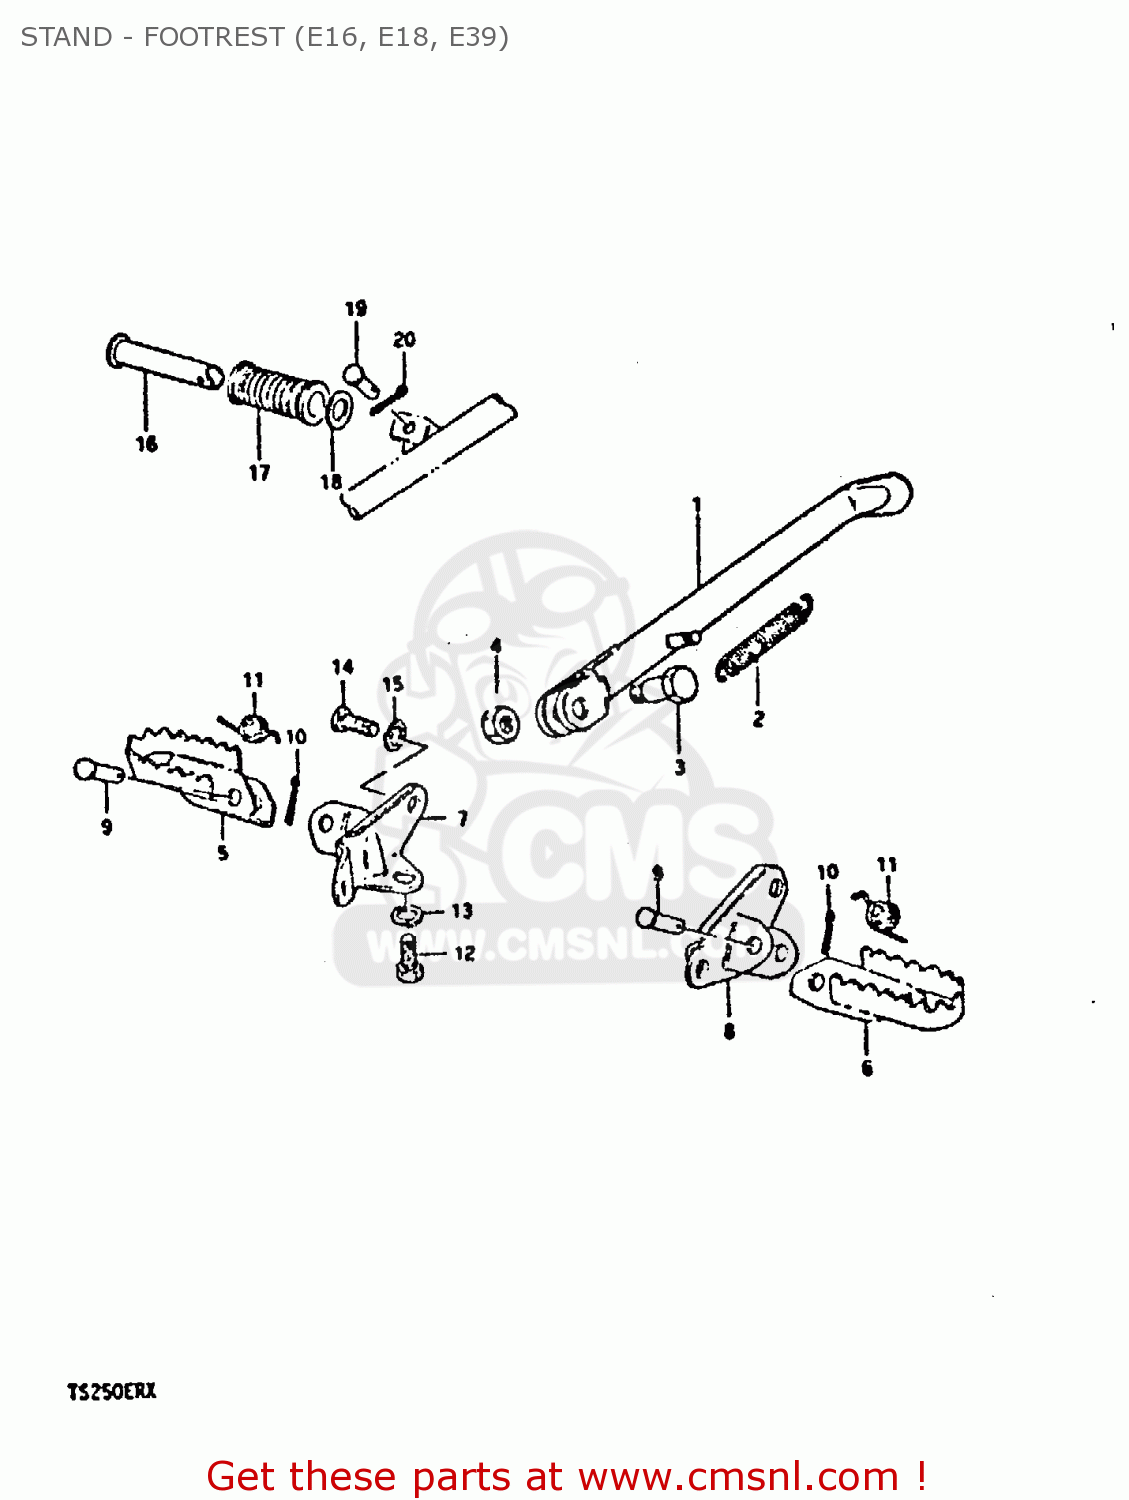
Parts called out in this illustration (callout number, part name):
1	STAND, PROP
2	SPRING
3	BOLT
4	NUT
5	HOLDER,FRONT FOOTREST,RIGHT
6	HOLDER,FRONT FOOTREST
7	FOOTREST,FRONT
8	FOOTREST
9	PIN
10	PIN 20X20
11	SPRING
12	BOLT
13	LOCK WASHER
14	BOLT 8X16
15	WASHER,LOCK,8.
16	BAR,FOOTREST RUBBER
17	RUBBER,PILLION FOOTREST
18	WASHER (19.5X32X2)
19	PIN
20	PIN 20X20
